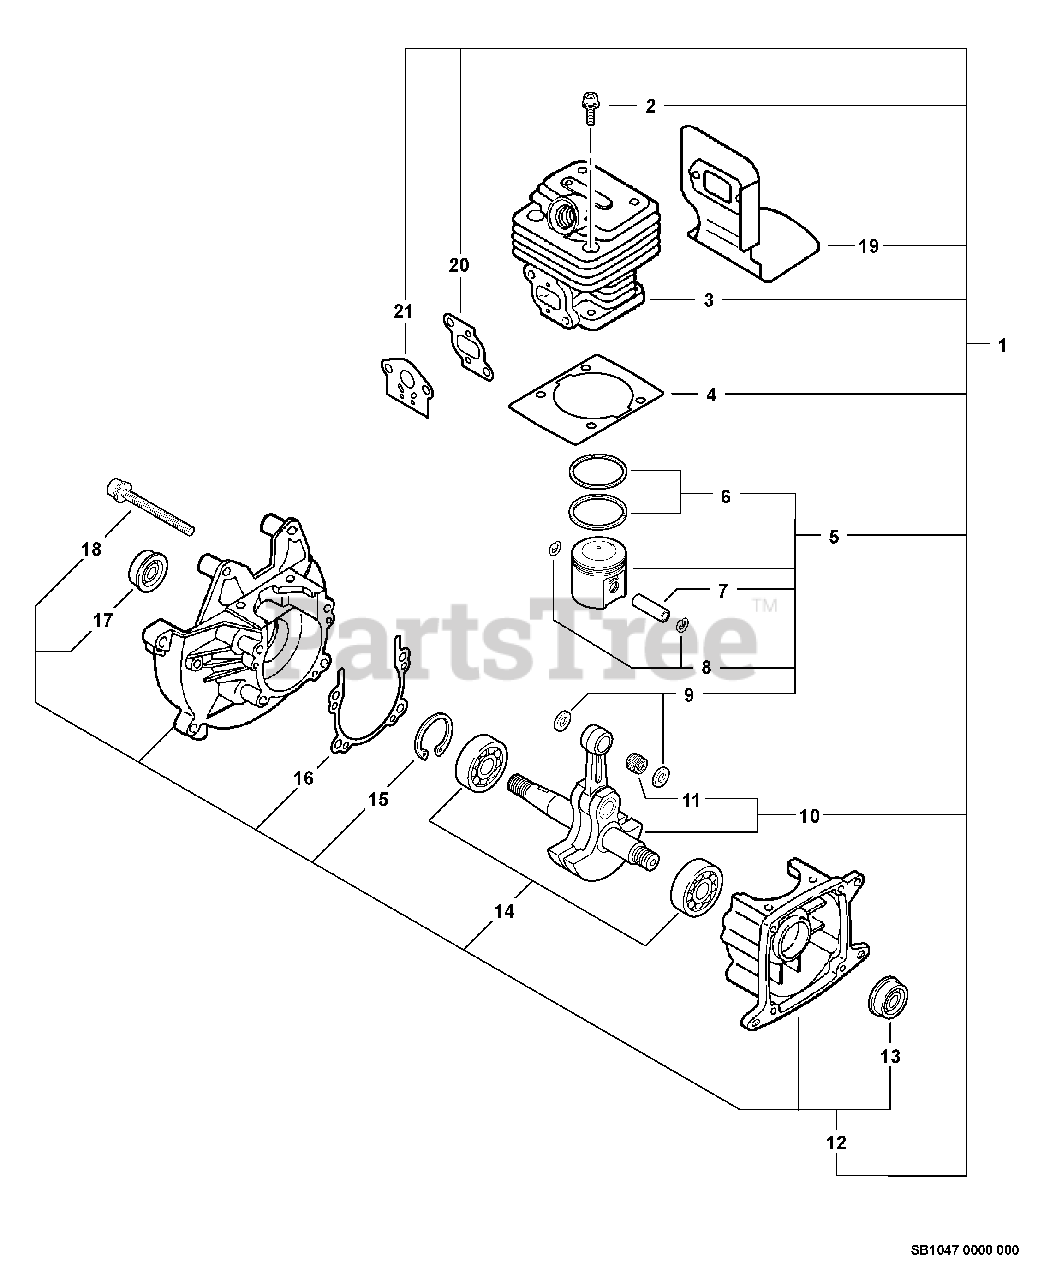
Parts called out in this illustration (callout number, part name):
1	SHORT BLOCK -- SB1047
2	SCREW - 5X22
3	CYLINDER
4	GASKET, CYLINDER
5	PISTON KIT
6	RING, PISTON
7	PIN, PISTON
8	RING, RETAINING
9	SPACER, PISTON
10	BEARING, NEEDLE - 8
11	CRANKSHAFT ASSY
12	CRANKCASE KIT
13	SEAL, OIL
14	BEARING, BALL - 6001C3
15	RING, RETAINING - 28
16	GASKET, CRANKCASE
17	SCREW - 5X25
18	SEAL, OIL - 12
19	SHIELD, EXHAUST
20	GASKET, INTAKE
21	GASKET, INTAKE
